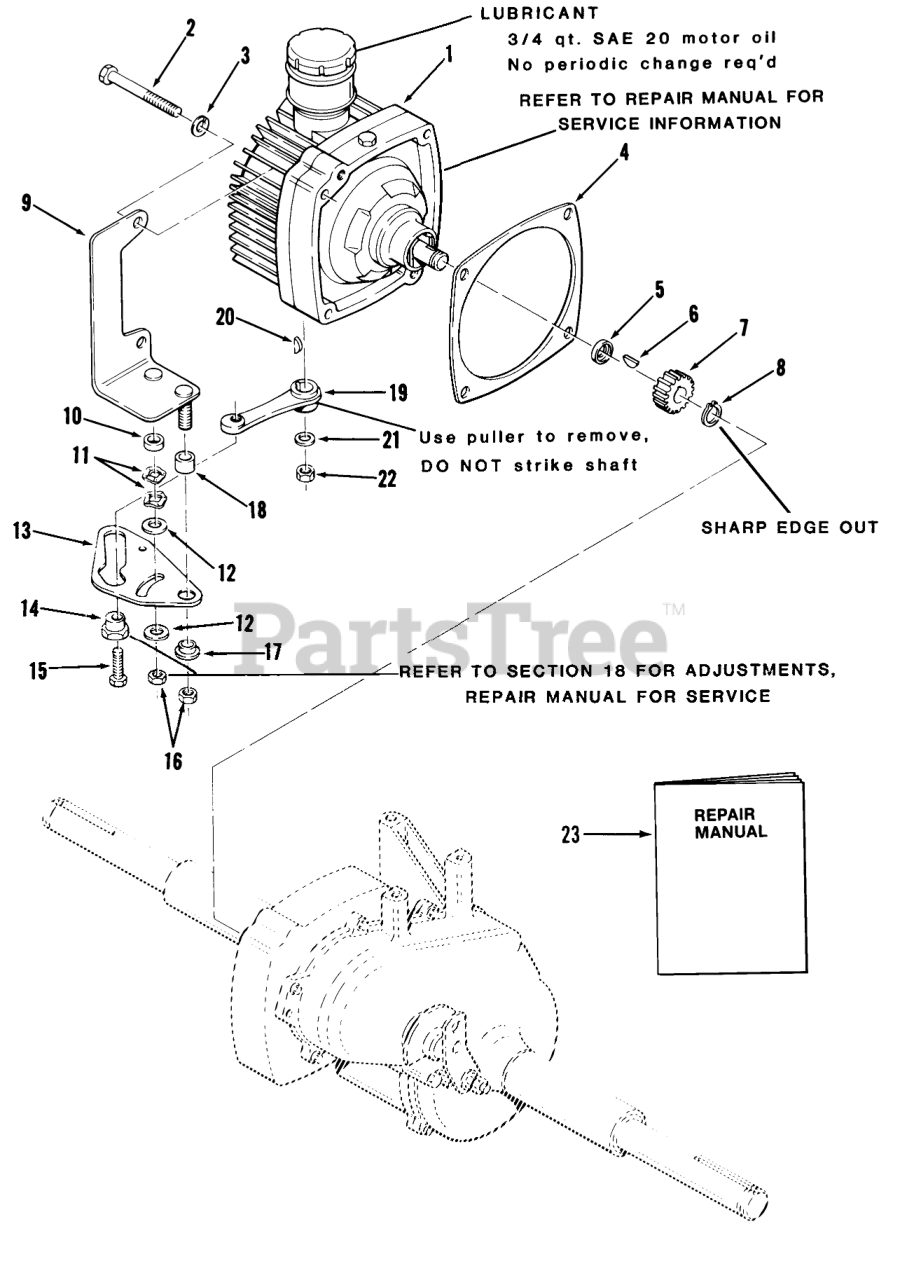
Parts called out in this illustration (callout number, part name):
1	Pump & Motor
2	Screw-Hex. Hd.
3	LOCKWASHER
4	GASKET HYDRO
5	SPACER-GEAR
6	KEY WOODR 1/8X1/2 DI
7	Gear 12 Tooth
8	SNAP RING
9	ASSY CONTROL SUPP R
10	SPACER-FRICTION
11	WASHER-SPRING DISC
12	FRICTION WASHER
13	CAM-SPEED CONTROL (NS)
15	Bolt
17	CAM-SPACER
18	SPACER-PIVOT
19	ARM-SPEED CONTROL
20	KEY WOODR 1/8X1/2 DI
21	Washer
22	Nut
23	Automatic Transmission Repair Manual
